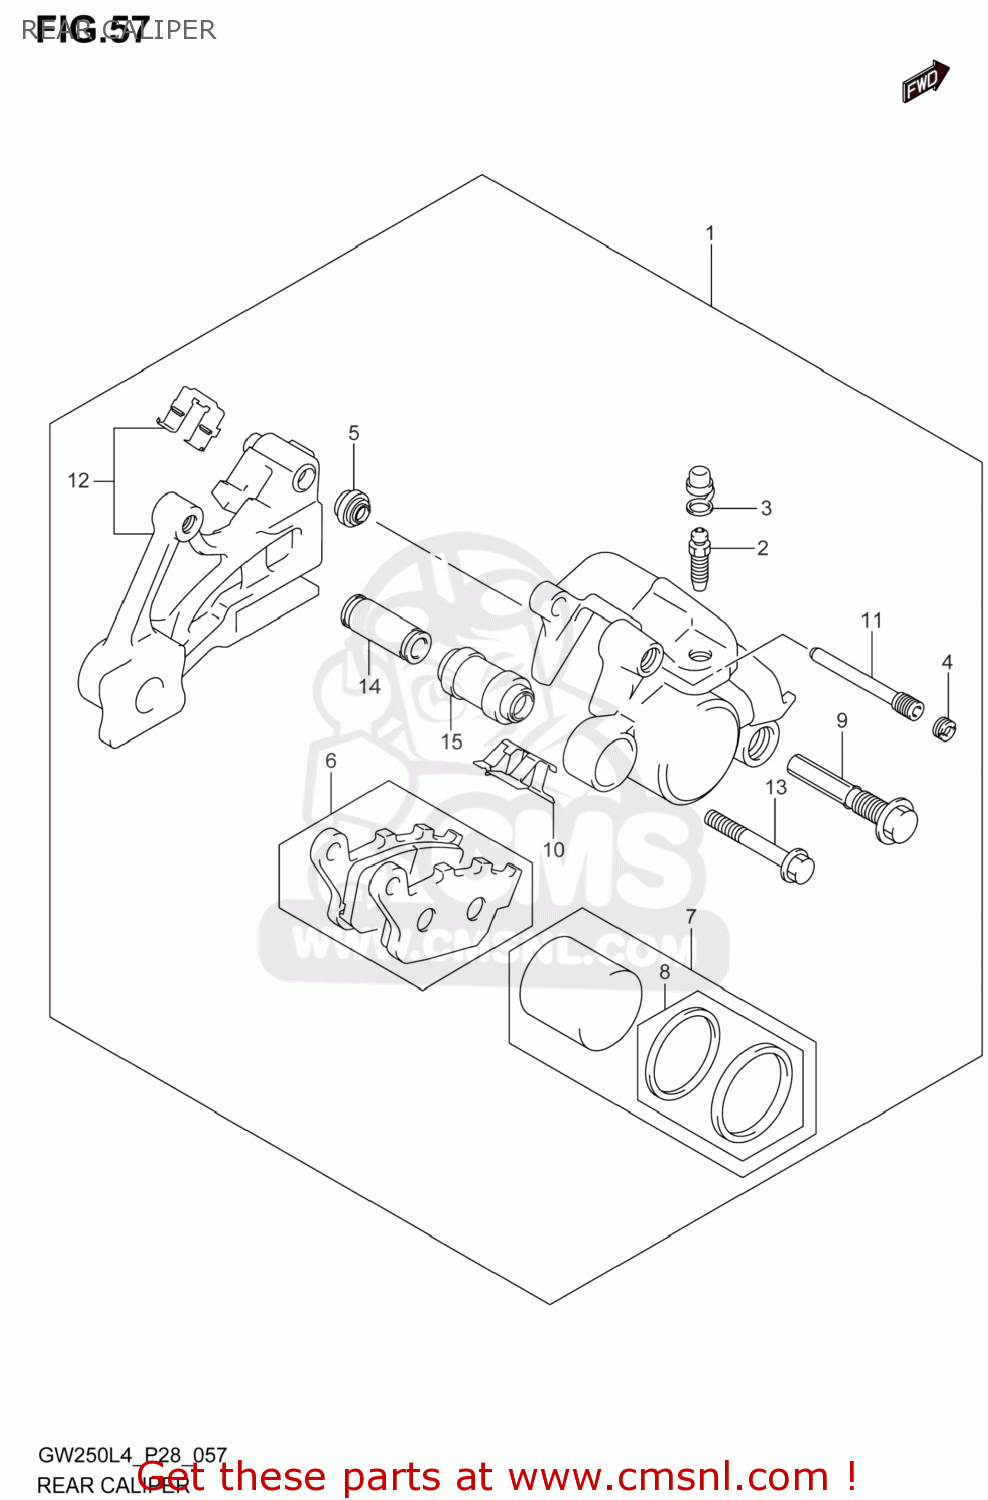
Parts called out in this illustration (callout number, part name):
1	CALIPER ASSY,RR
2	BLEEDER
3	CAP,BLEEDER
4	PLUG,PIN
5	BOOT
6	PAD SET (NAS)
7	PISTON SET
8	SEAL SET,PISTON
9	BOLT
10	SPRING,PAD
11	PIN,PAD
12	BRACKET
13	BOLT
14	SLEEVE
15	BOOT,SLEEVE
